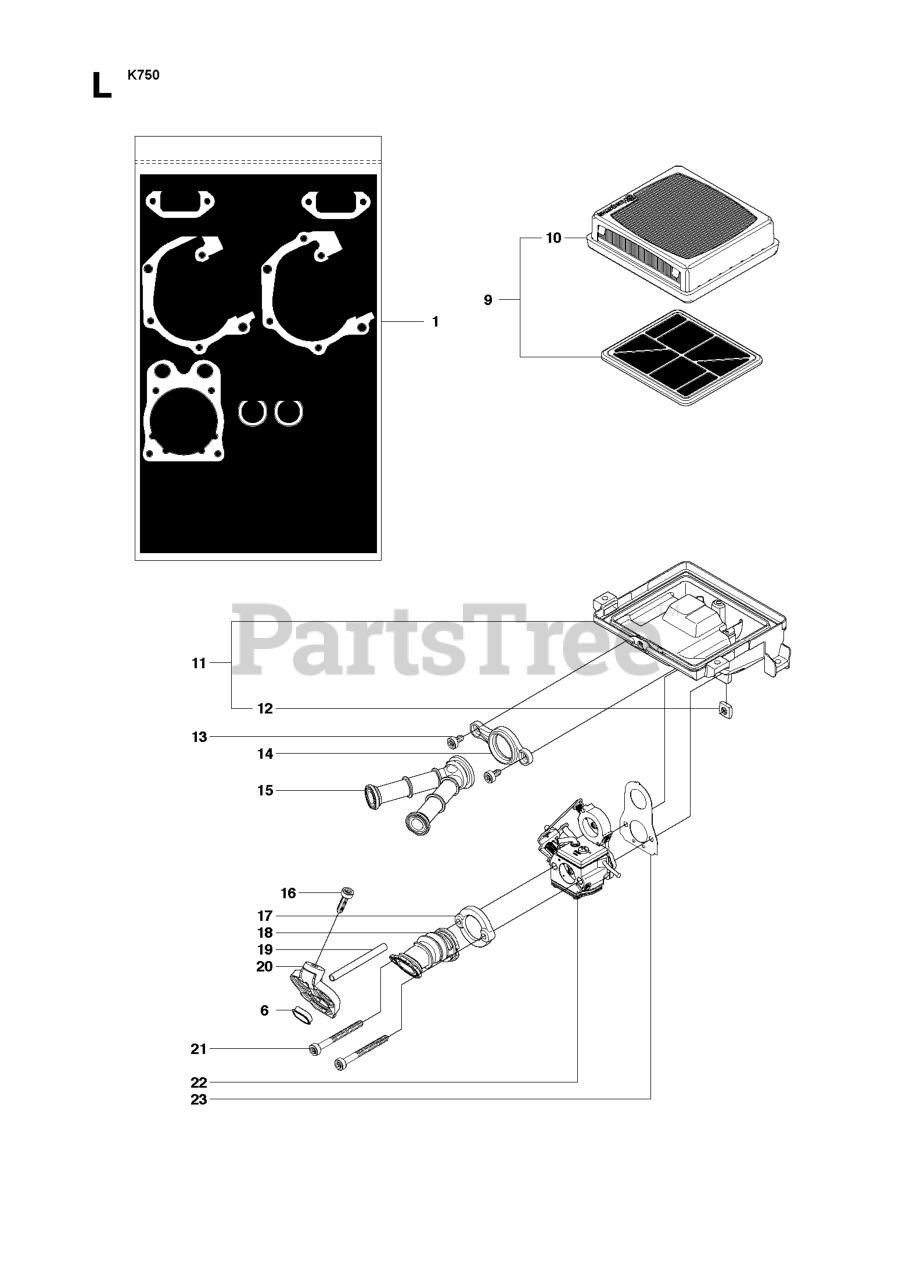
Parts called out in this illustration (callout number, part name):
1	GASKET KIT
3	GASKET
7	SEALING RING
10	AIR FILTER PAPER
11	CARBRETOR BRACKET
15	RP INLET PIPE
17	FLANGE
18	RP INLET PIPE
19	RP HOSE
20	PLATE, INLET ASSY
22	CARBURETOR
23	RP GASKET CARBURETOR
